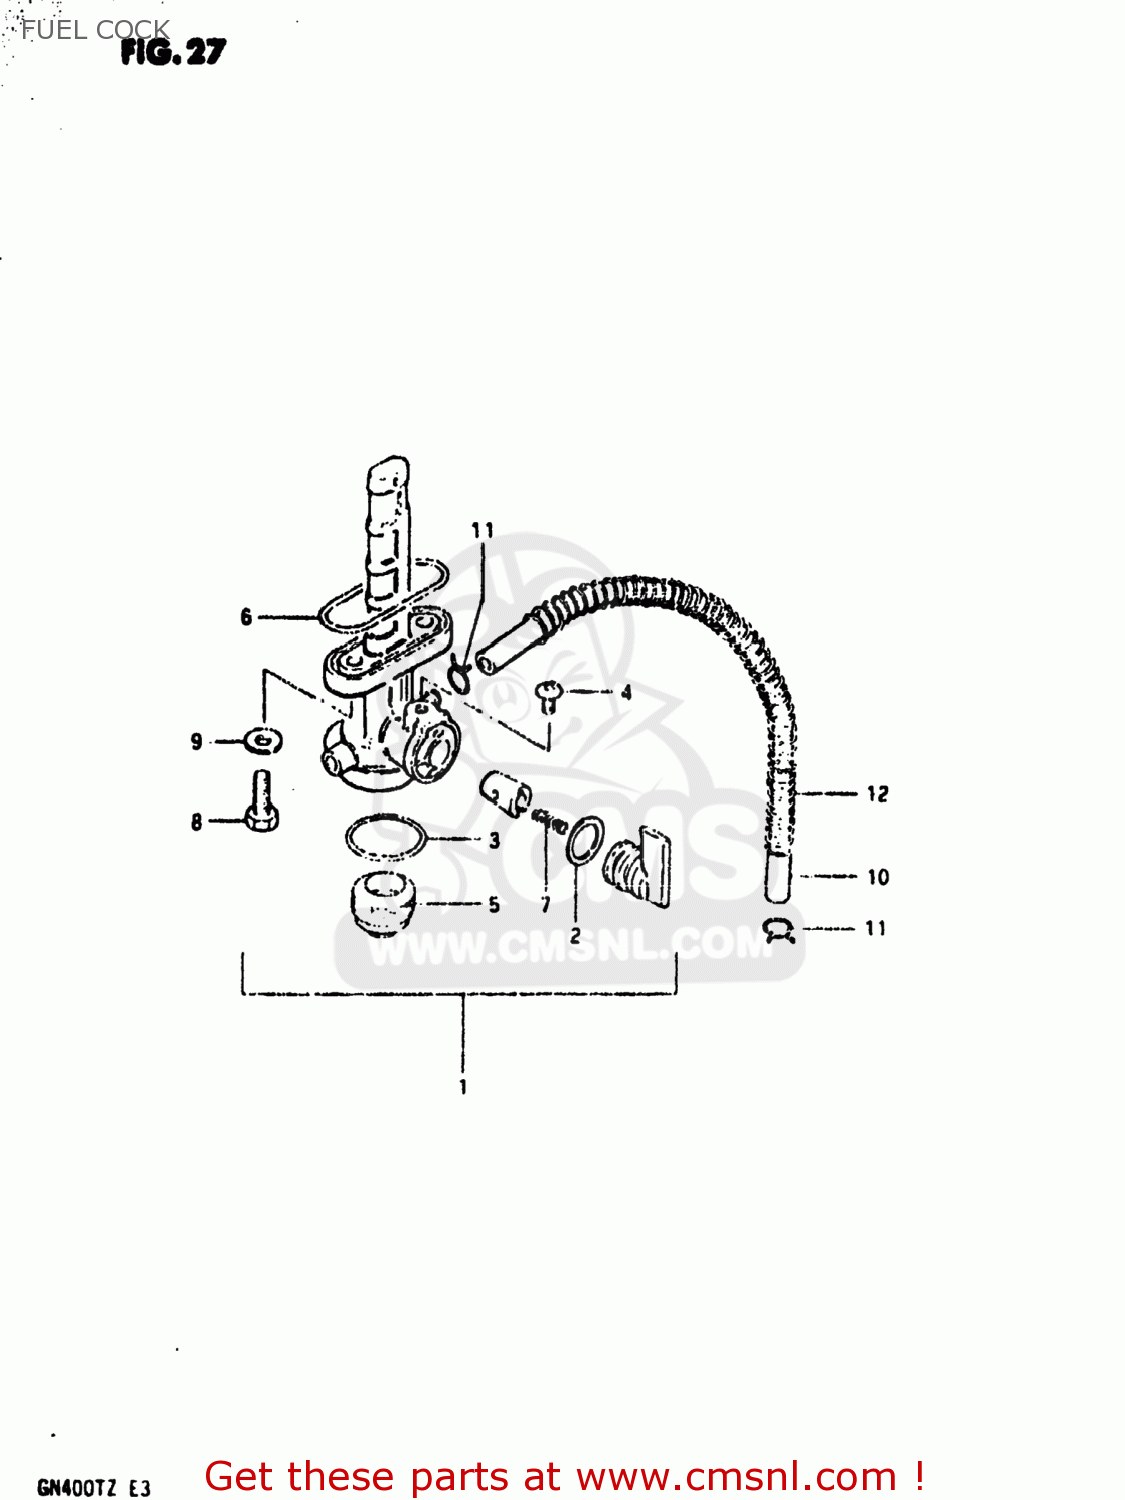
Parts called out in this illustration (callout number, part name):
1	COCK ASSEMBLY,FUEL
2	O-RING
3	GASKET,FILTER (NAS)
4	SCREW,FUEL COCK LEVER
5	CUP,STRAINER
6	O RING,FUEL COCK
7	SPRING
8	BOLT(6X20)
9	GASKET
10	HOSE
11	CLIP
12	SPRING
